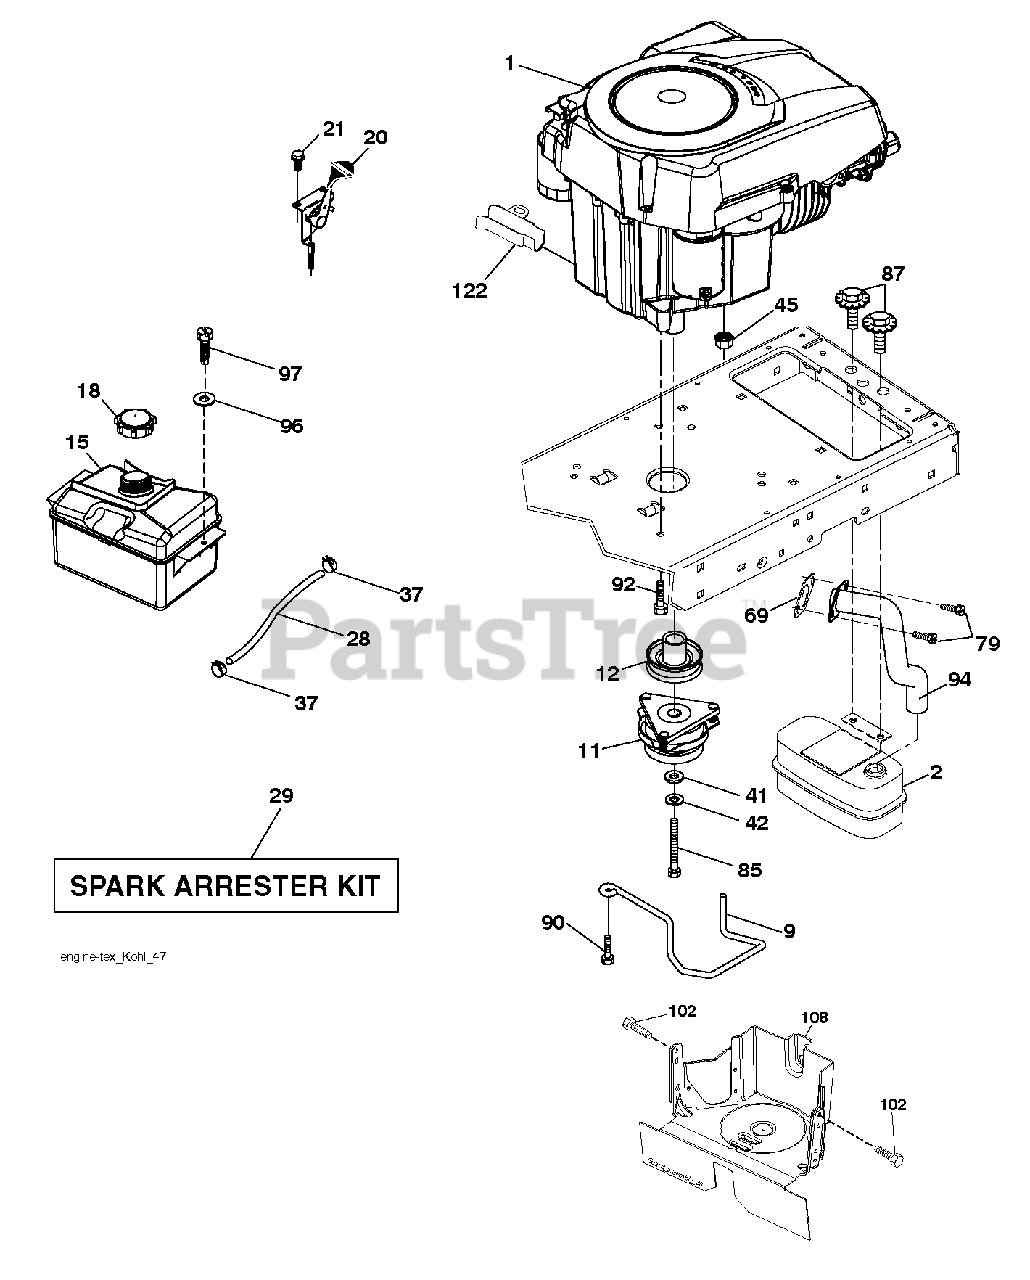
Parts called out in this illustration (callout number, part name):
2	MUFFLER.SINGLE.CYL.KOHL/B&S
9	KEEPER.BELT.ENGINE.4.2
11	CLUTCH.ELECTRIC.LT.48"*
12	PULLEY.ENGINE.TUFFTORQ
15	RP TANK FUEL FRT 1.5 GAL
18	CAP ASM.FUEL.2.25"FR.
20	CONTROL.TH/CK.C.
21	SCREW.#10 X 0.750.BOS
28	LINE.FUEL.20
29	KIT.SPARK ARRESTOR 794945 B&S
37	HOSE CLAMP
42	LOCKWASHER
45	NUT
69	GASKET.EXHAUST.KOHLER
79	SCREW.SOCKET HD.5/16-1
85	BOLT HEX 7/16-20X4-1/4"
87	Bolt, 5/16-18 X 1-3/4
90	SCREW 3/8-16X1
92	SCREW 3/8-16X1
94	RP.TUBE.EXHAUST.KOHL.COURAGE
97	SCREW HEXWSHR 1/4-20X3/4
102	SCREW 5/16-18X1
108	COVER PULLEY
122	EXTENSION DRAIN OIL
